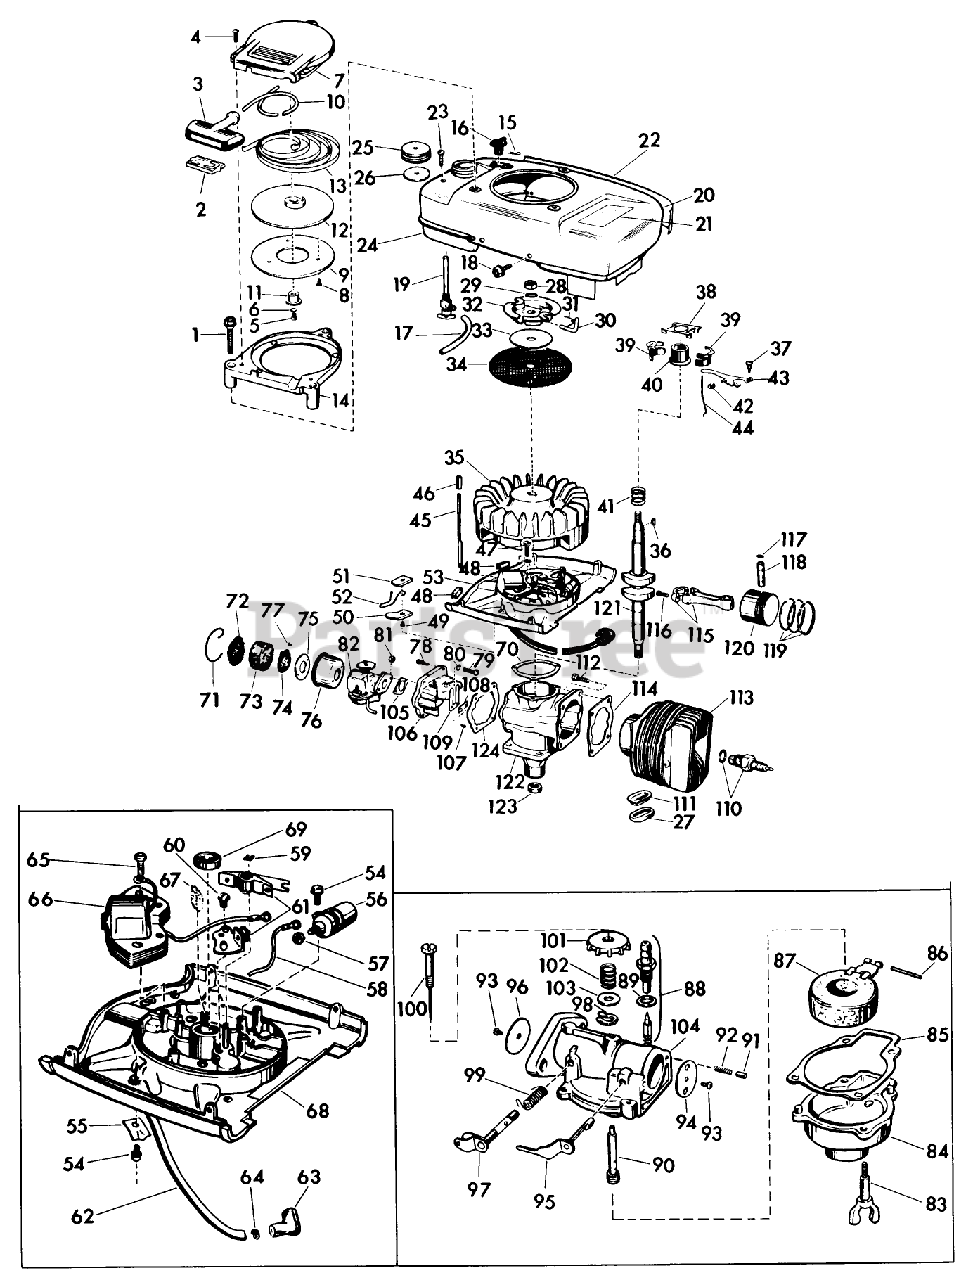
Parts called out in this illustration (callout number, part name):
5	Screw-Pulley to Cap
13	RECOIL SPRING
14	Base-Starter
15	Cotter Pin-Choke Knob
16	KNOB, CHOKE BAR
18	SCREW S
19	Shut-off Valve and Screen Assembly
22	Decal-"Lawn-Boy"
25	Gas Cap
30	PIN - STARTER
40	COLLAR S
41	Spring-Governor
42	WEAR BLOCK S
43	GOVERNER LEVER AY
44	GOVERNOR ROD S
49	Screw Shut-off Switch
59	Spring Clip-Breaker Post
61	BREAKER AY. S
63	Cover-Rubber
67	Oiler Wick
70	GASKET S
73	ELEMENT
75	BACK-UP PLATE
78	SCREW S
81	STOP NUT
93	Screw-Choke Disc
95	CHOKE SHAFT&LVR AY
100	NEEDLE AY. S
102	Spring-Ndl. Adj.
105	GASKET S
108	PLATE-BACKUP, REED
110	Spark Plug
116	Screw-Connecting Rod
121	Crankshaft
